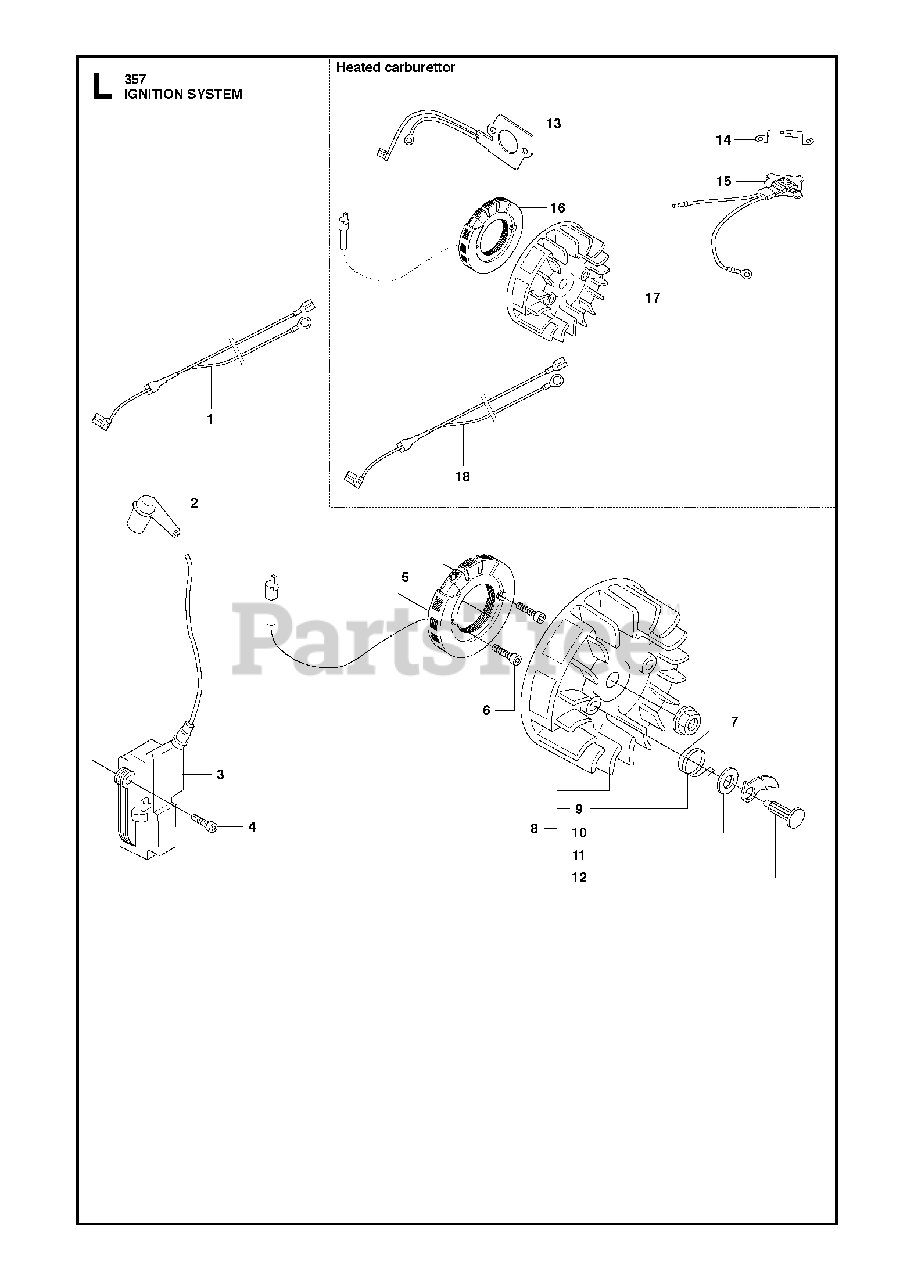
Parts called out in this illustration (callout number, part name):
1	CABLE ASSY
2	SPARK PLUG CONN. KIT
3	IGNITION MODULE
5	GENERATOR
7	NUT W/ WASHER
8	FLYWHEEL
9	SPRING
10	WASHER
11	PAWL
12	SCREW
13	Heating Plate
14	RETAINER
15	THERMOSTAT ASSY
16	GENERATOR STATOR
17	FLYWHEEL
18	WIRING ASSY
